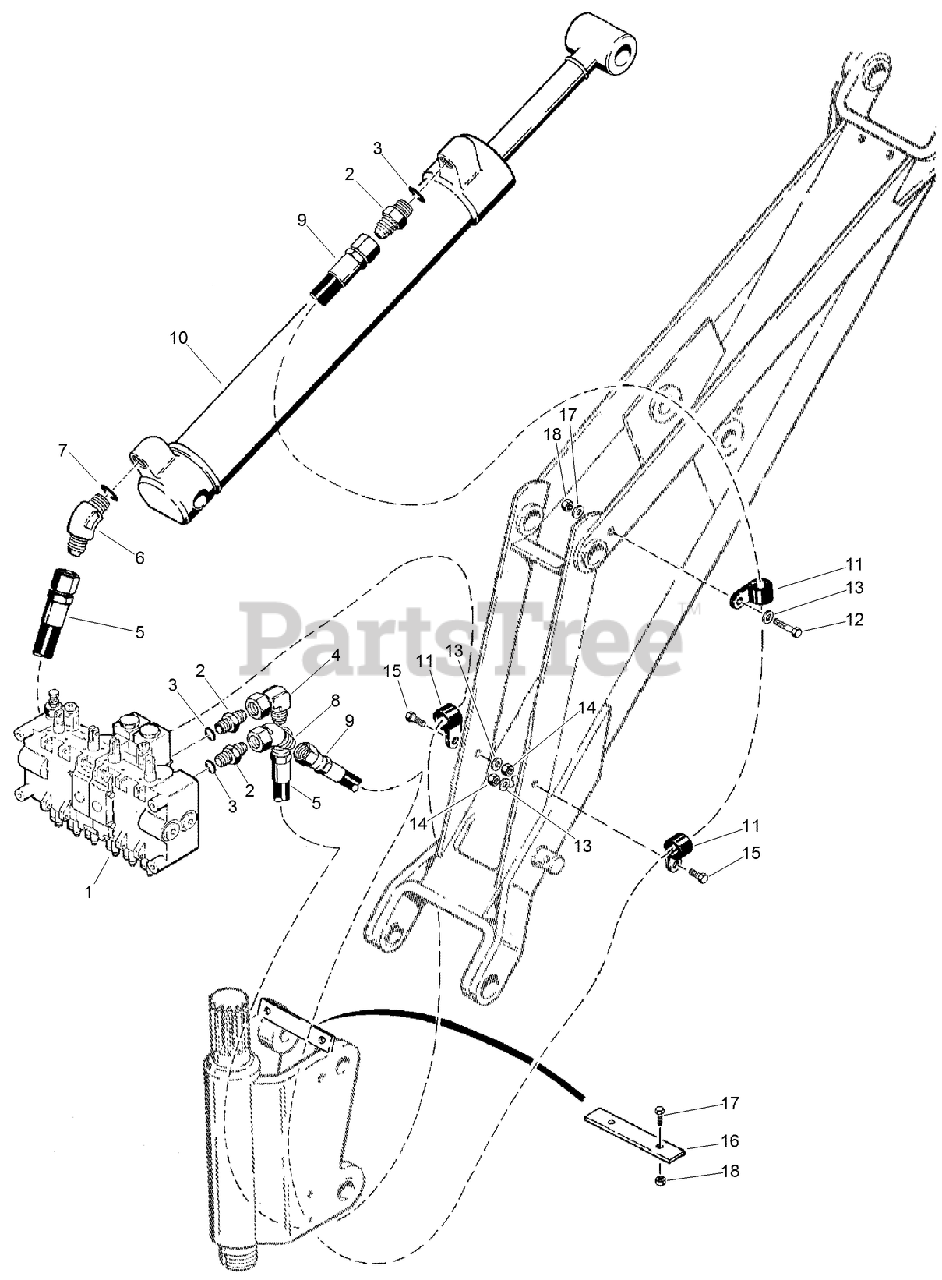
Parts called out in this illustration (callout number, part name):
1	VALVE-Backhoe, w/Special Low Leak Spools
2	CONNECTOR-Str Thd 1/2, 37FL-ORB 1/2
3	O-RING
4	ELBOW-90 Swivel 37FL 1/2 Tube
5	HOSE-1600 mm (63 inch) long, to closed end of dipper cylinder
6	ELBOW-45 degree, 3/4-16 inch flare x adj O-ring boss
7	O-RING
8	ELBOW-45 degree, 3/4-16 inch flare x swivel
9	HOSE-2200 mm (86-5/8 inch) long, to rod end of dipper cylinder
10	CYLINDER-Backhoe
11	CLAMP-Tube
12	BOLT-Hex Hd 0.250 x 1.00 GR8 ZND
13	WASHER-FLAT
14	NUT-Prev Trq 1/4 GRA CAD NONDIR
16	BRACKET-Hose Mtg
17	BOLT-Hex Hd 0.250 x 1.50 GR8 ZND
18	NUT-Prev Trq 1/4 GRA CAD NONDIR
